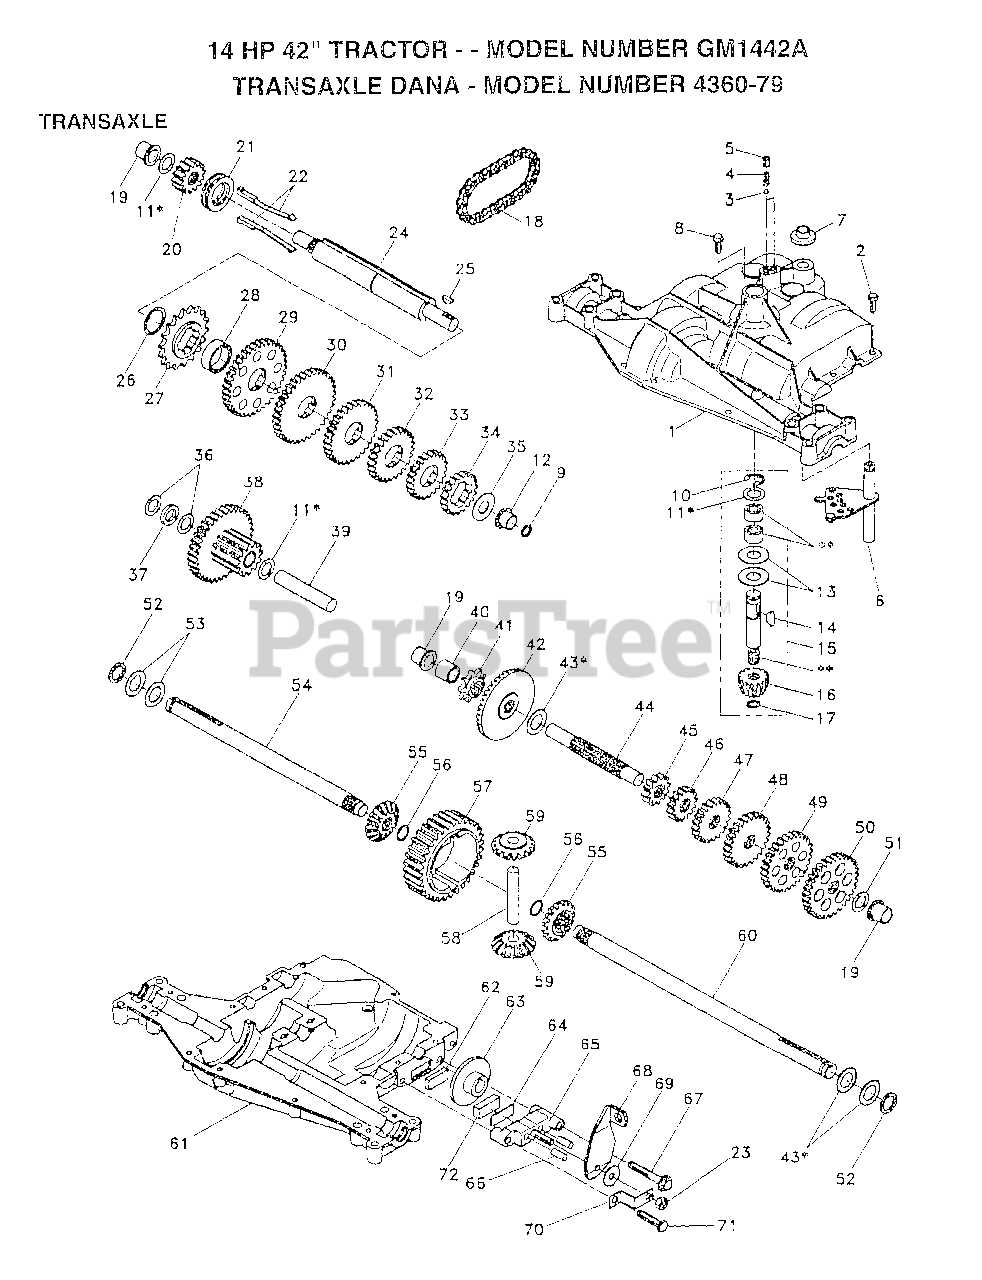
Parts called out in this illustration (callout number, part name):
1	HOUSING UPPER TRN
4	"SPRING, DETENT LT"
5	"SCREW, SET LT"
6	KIT SHIFTER ASM
7	SHIFTER BOOT
8	SCREW TAP W/SEAL
9	SQUARE RING
11	ASM KIT SHIM 4689
12	BEARING FLAN-DANA
13	WASHER T
14	KEY WOODRUFF-DANA
15	AS KIT INPUT SHFT
16	PINION 14T T
17	"RING,RETAINING LT"
18	"CHAIN,24 PTCH LT"
19	BEARING.FLNG.5510
20	GEAR SPUR 14 TTH
21	COLLAR CLUTCH
22	ASM KIT CLTCH KEY
23	NUT.LOCK.5/16-24
24	SHAFT INTERM DANA
25	WOODRUFF KEY
26	"RING,RETAINING LT"
27	SPROCKET 18T T
28	SPACER YT
29	GEAR SPUR 37 TTH
30	GEAR SPUR 35 TTH
32	GEAR 25T LT
33	GEAR SPUR 22 TT
34	SPUR GEAR 19T
35	"WASHER, PLAIN LT"
36	WASHER 025
37	SPACER
38	ASSM GEAR COMB
39	SHAFT IDLER
40	SPACER T
41	SPROCKET 9T LT
43	ASM KIT SHIM
44	SHAFT T
45	GEAR SPUR 12 TTH
46	GEAR SPUR 15 TTH
48	"GEAR, SPUR 25T LT"
49	GEAR 28T T
50	"GEAR, SPUR 31T LT"
51	WASHER 060
52	NEOPRENE WASHER
53	WASHER 031
55	GEAR 15T T
56	"RING,RETAINING LT"
58	SHAFT T
59	GEAR 1ST T
61	HOUSING LOWER TNS
62	PUCK T
63	BRAKE DISC. T
64	SPACER LT
66	PIN T
69	WASHER LT
71	"SCREW, TAPPING LT"
72	PUCK T
